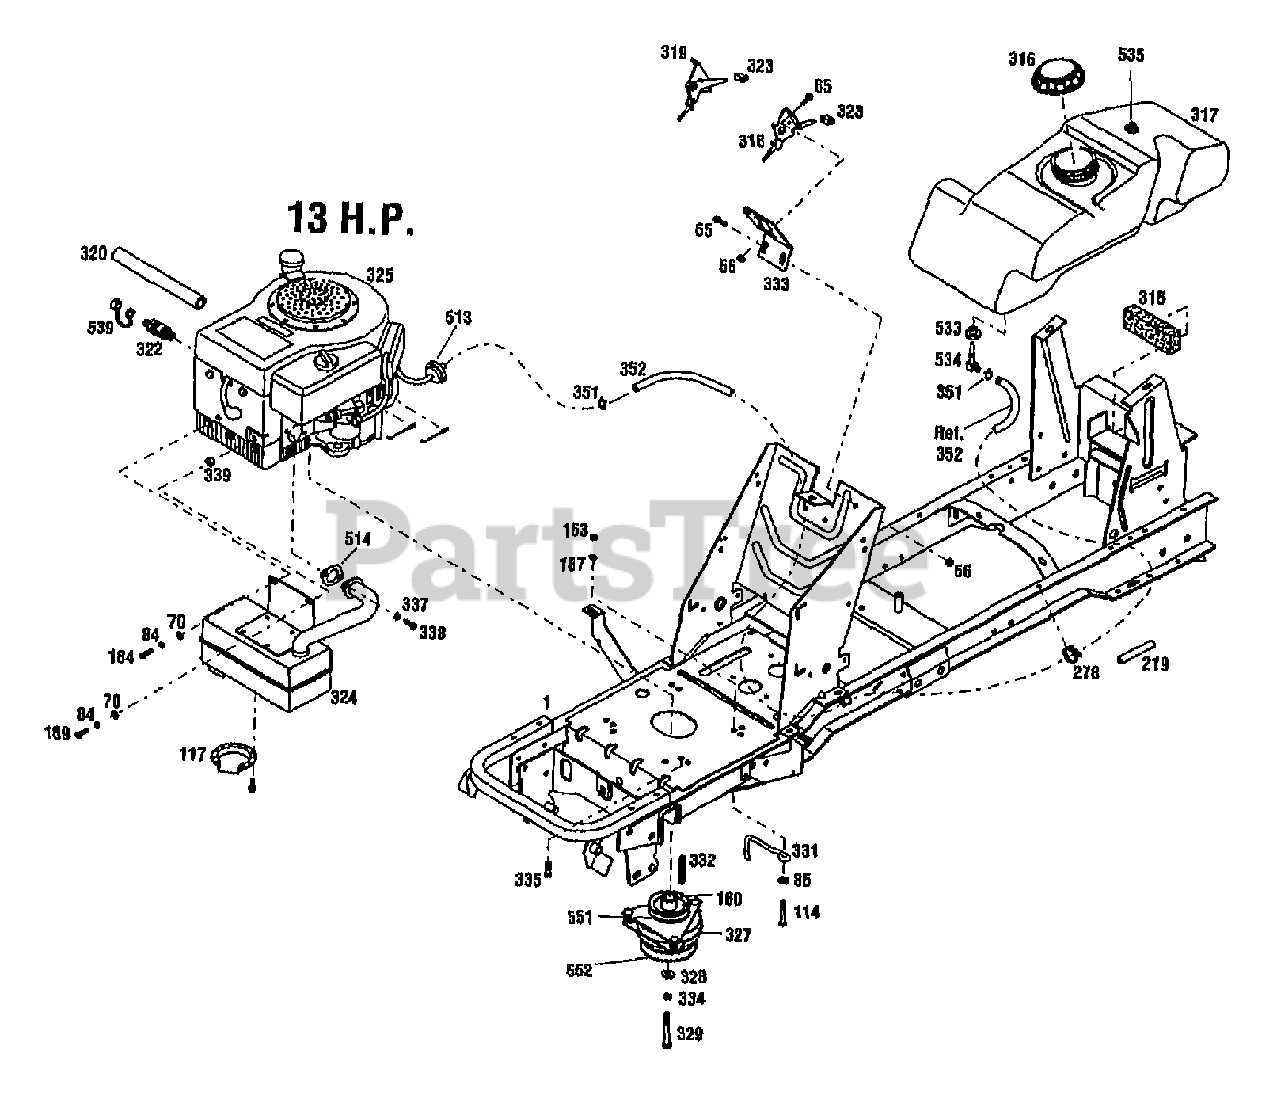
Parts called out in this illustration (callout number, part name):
1	ASSM-FRAME LTX
56	NUT-HF/LK 1/4-20 ZP
65	SCR-HH 1/4-20X.625
70	WASHER-FLAT 1/4 SAE
84	WASHER-LK .25 ZP
85	WASHER-FLAT 3/8 SAE
114	SCR-THRD FRM 3/8-16X1.50
117	DEFLECTOR-MUFFLER
160	PULLEY-ENGINE
163	NUT-HEX 3/8-16 ZP
167	WASHER-LK .375 @ DEPL
184	SCR-HH 1/4-20 X .875
189	SCR-HH 1/4-20X1.25
278	TIE-CABLE NYLON BLACK
315	PAD-FUEL TANK
316	CAP-FUEL
317	TANK-FUEL
318	CONTROL-THROTTLE
319	CONTROL-CHOKE
320	HOSE-OIL DRAIN
322	ASSM-OIL VALVE
324	MUFFLER
325	ENGINE, 13 HP, MODEL 28N707
327	CLUTCH-ELECTRIC
328	WASHER-SPEC 1.42X.468X.25 ZP
329	SCR-HH 7/16-20X3.00
331	CLUTCH-RETAINER
332	KEY-.25 SQ X 2.5
333	BRKT-MOUNTING CONTROL
334	WASHER-LK .438 ZP
335	SCR-HH 3/8-16X1.0 THDFM
337	WASHER-LOCK
339	SPACER-.625X.344X.34
351	CLAMP-HOSE
352	LINE-FUEL
513	FILTER-FUEL
514	MUFFLER GASKET
533	BUSHING-RUBBER
534	ELBOW-90 DEG (FUEL LINE)
535	VENT-FUEL TANK
539	CAP-OIL DRAIN
551	BEARING-UPPER CLUTCH
552	BEARING-CLUTCH LOWER
